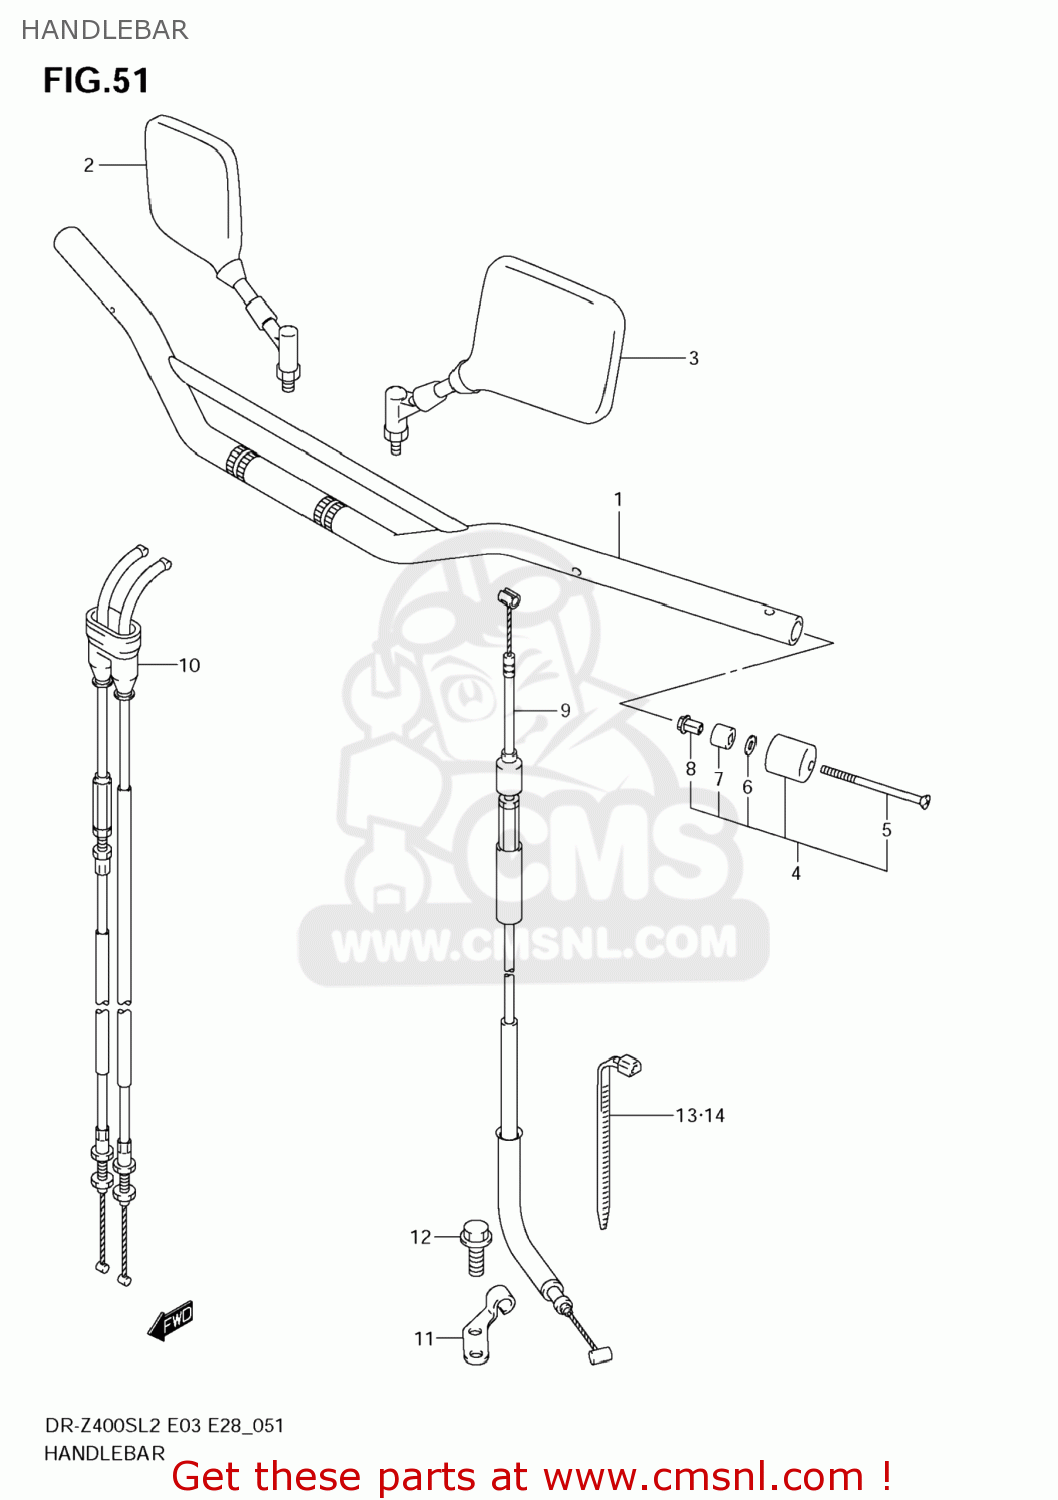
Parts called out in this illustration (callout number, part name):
1	HANDLEBAR(SILVER)
2	MIRROR ASSY,RR VIEW,R
3	MIRROR ASSY,RR VIEW,L
4	BALANCER SET,HANDLEBAR
5	SCREW
6	WASHER(6.5X16X4)
7	EXPANDER,HANDLE BALANCER
8	NUT,HANDLE BALANCER
9	CABLE ASSY,CLUTCH
10	CABLE SET,THROTTLE
11	STOPPER,CLUTCH CABLE
12	BOLT
13	CLAMP(L:100)
14	CLAMP(L:235)
